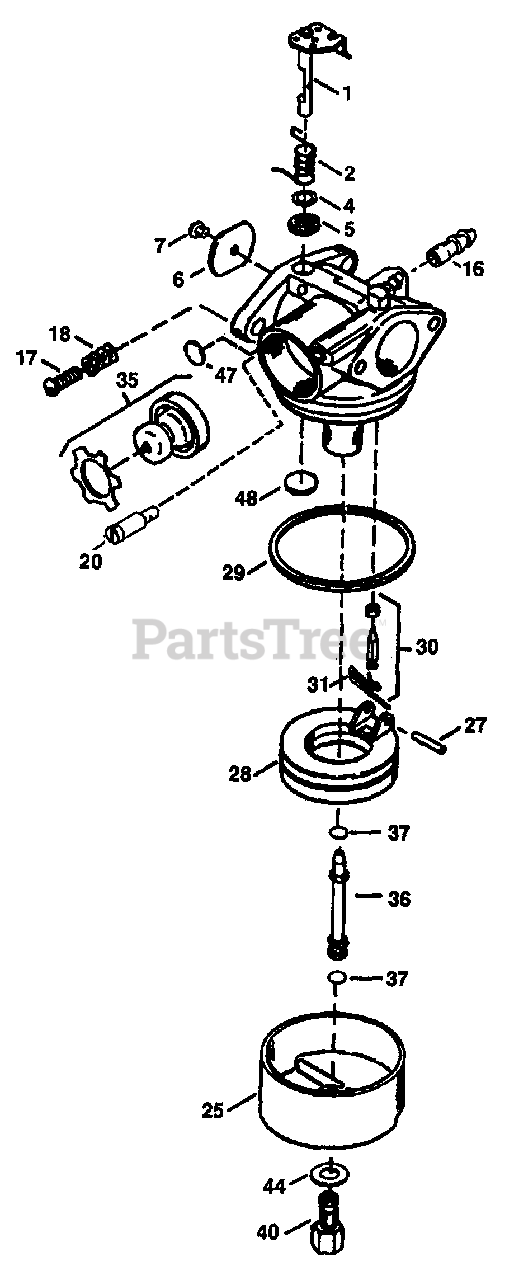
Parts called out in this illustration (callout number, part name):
1	Throttle Shaft & Lever Assy
2	Throttle Return Spring
4	Dust Seal Washer
5	Dust Seal
6	Throttle Shutter
7	Shutter Screw
16	Fuel Fitting
17	Throttle Crack Screw/Idle Speed Screw
18	Tension Spring
20	Idle Restrictor Screw
25	Float Bowl
27	Float Shaft
28	Float
29	Float Bowl "O" Ring
30	Inlet Needle, Seat & Slip
31	Spring Clip
35	Primer Bulb/Retainer Ring
36	Main Nozzle Tube
37	"O" Ring, Main Nozzle Tube
40	High Speed Bowl Nut
44	Bowl Nut Washer
47	Welch Plug, Idle Mixture Well
48	Welch Plug, Atmospheric Vent
